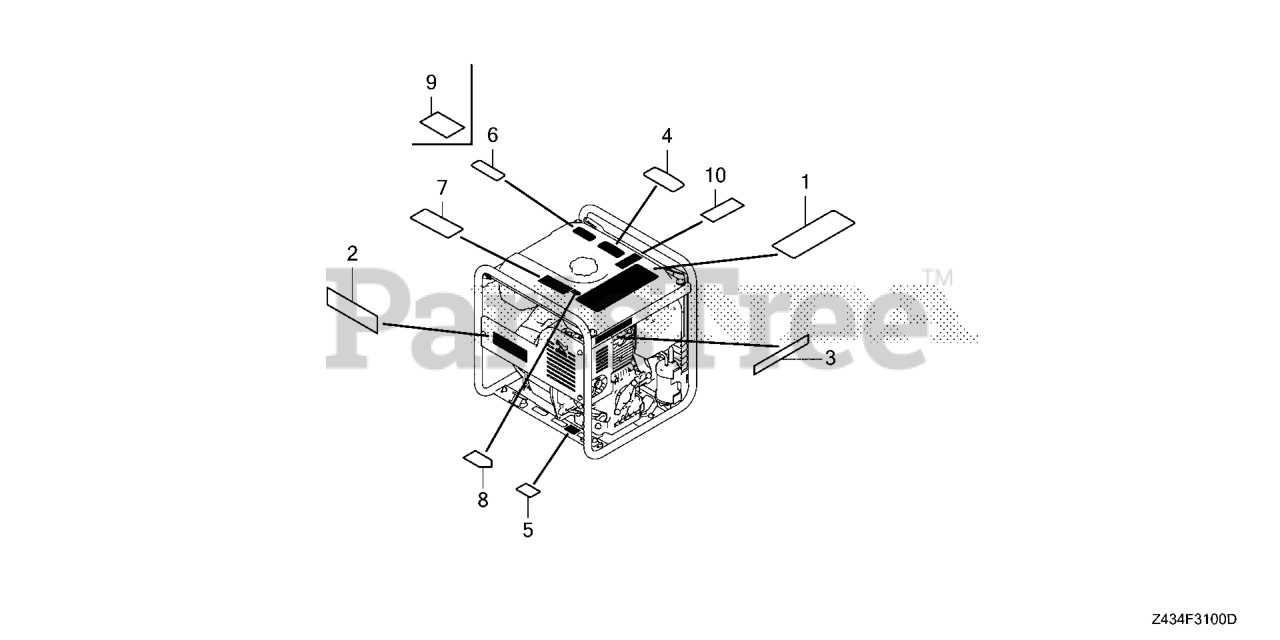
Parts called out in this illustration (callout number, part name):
1	MARK, CAUTION
2	LABEL, SPECIFICATION
3	MARK, SPARK ARRESTER WARNING
4	MARK, FUEL INDICATION
5	MARK, OIL CAUTION
7	LABEL, FUEL WARNING (ENGLISH)
